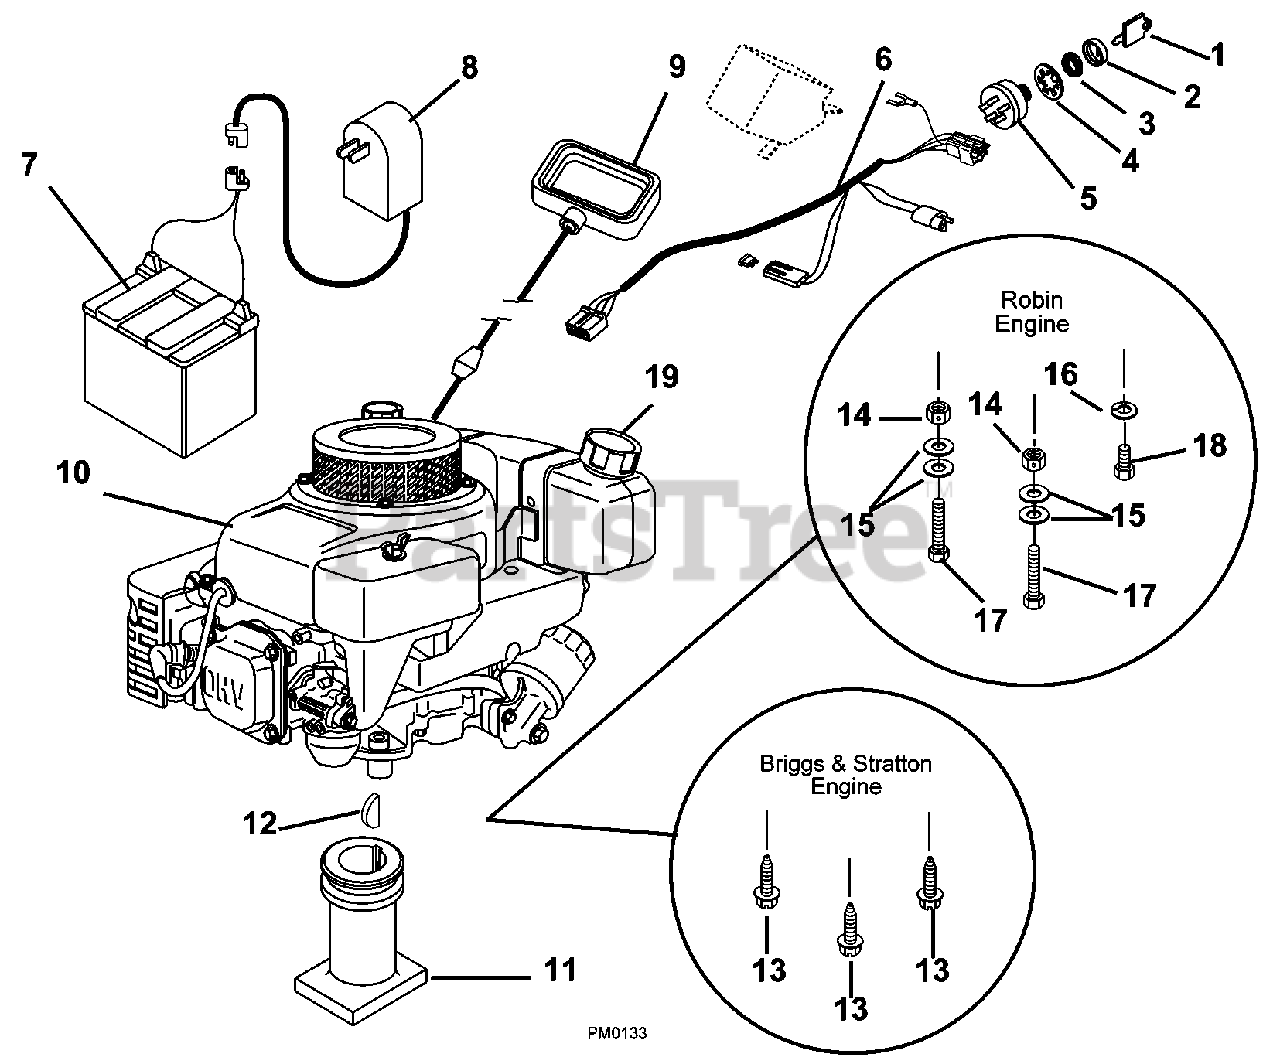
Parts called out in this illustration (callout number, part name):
1	Key with Cap (580 RSE)
2	Cap-Ignition Switch (580 RSE)
3	Nut, Panel .625-32 (580 RSE)
4	Washer-Locking Internal .625 x .045 (580 RSE)
5	Switch, Key Electric Start-LM (580 RSE)
6	Harness, Wire LM-Electric (580 RSE)
7	Battery (515)(580 RSE)
8	Battery Charger (580 RSE)
9	Recoil Start Handle
10	Engine, Robin 6 HP 4 Cycle (600 C)
11	Adapter, Blade .875 Dia with Keyway (580 R, 580 RS, RSE, RSW)
12	Key-Woodruff .156 x .625 x .25 SAE #6 (580 R, 580 RS, 580 RSE, 580 RSW)
13	Screw-Tapping .38-16 x 1.00 Hex Washer Head
14	Nut-Locking-Center .31-18 (600 C)
15	Washer-Flat-Steel .312 x .734 x .065 (600 C)
16	Washer-Locking .312 x .097 Heavy (600 C)
17	Bolt-Hex .31-18 x 1.25 Grade 5 (600 C)
18	Bolt-Hex .31-18 x .75 Grade 5 (600 C)
19	Fuel Cap
